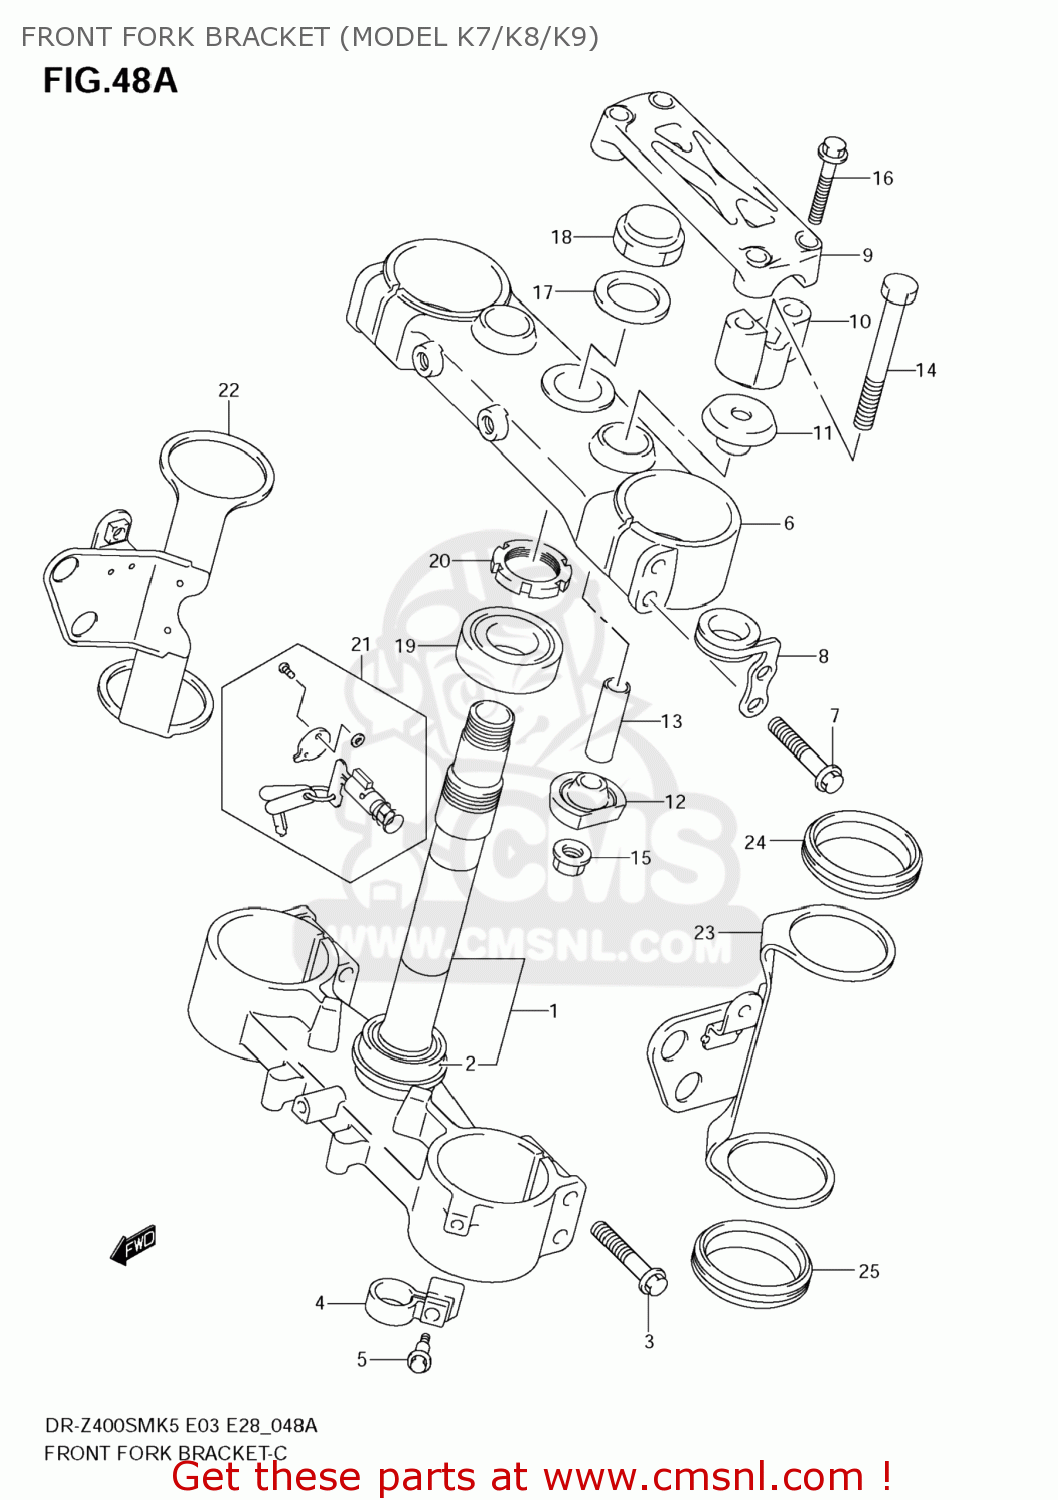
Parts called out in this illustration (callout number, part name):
1	BRACKET,UNDER
2	BEARING(30X52X16)
3	BOLT
4	GUIDE,FR BRAKE HOSE
5	BOLT(6X20.5)
6	BRACKET,UPR
7	BOLT
8	GUIDE,CABLE
9	HOLDER,HANDLEBAR UPR
10	HOLDER,HANDLE LWR
11	CUSHION,RUBBER
12	CUSHION,RUBBER UNDER
13	SPACER
14	BOLT
15	NUT
16	BOLT
17	WASHER,STEM HEAD
18	NUT
19	BEARING(30X52X16)
20	NUT,STEERING
21	LOCK ASSY,STEERING(NEIMAN)
22	BRACKET,HEADLAMP HOUSING,R
23	BRACKET,HEADLAMP HOUSING,L
24	DAMPER,HEADLAMP BRACKET UPR
25	DAMPER,HEADLAMP BRACKET LWR
